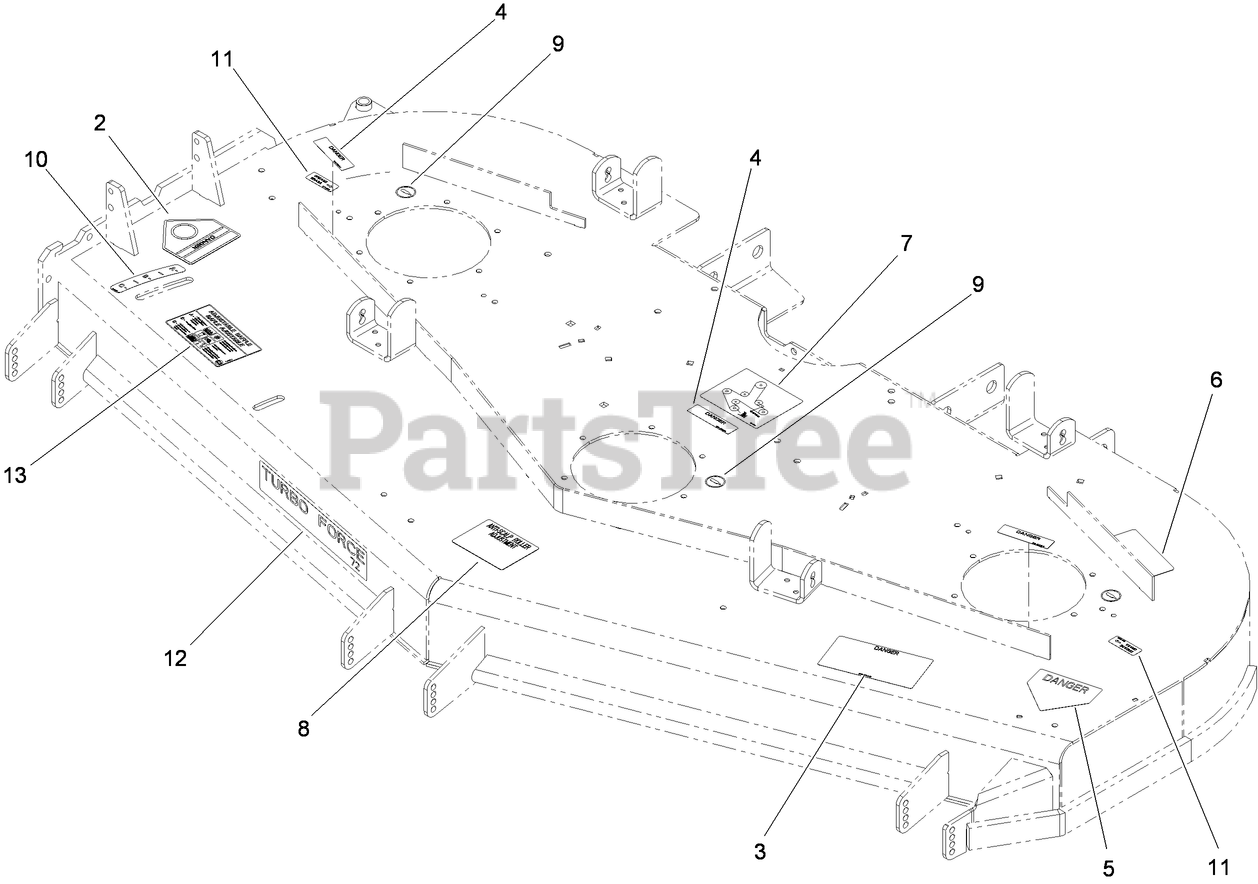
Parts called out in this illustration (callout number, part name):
2	DECAL-DANGER
3	DECAL-DANGER, THROWN OBJECT
4	DECAL-COVER, MISSING
5	DECAL-DANGER
6	DECAL-TORQUE
7	DECAL-ROUTING, BELT
8	DECAL-SCALP, ANTI
9	DECAL-GREASE
10	DECAL-SETTING, BAFFLE
11	Decal-Grease
13	DECAL-ADJUSTMENT, BAFFLE
